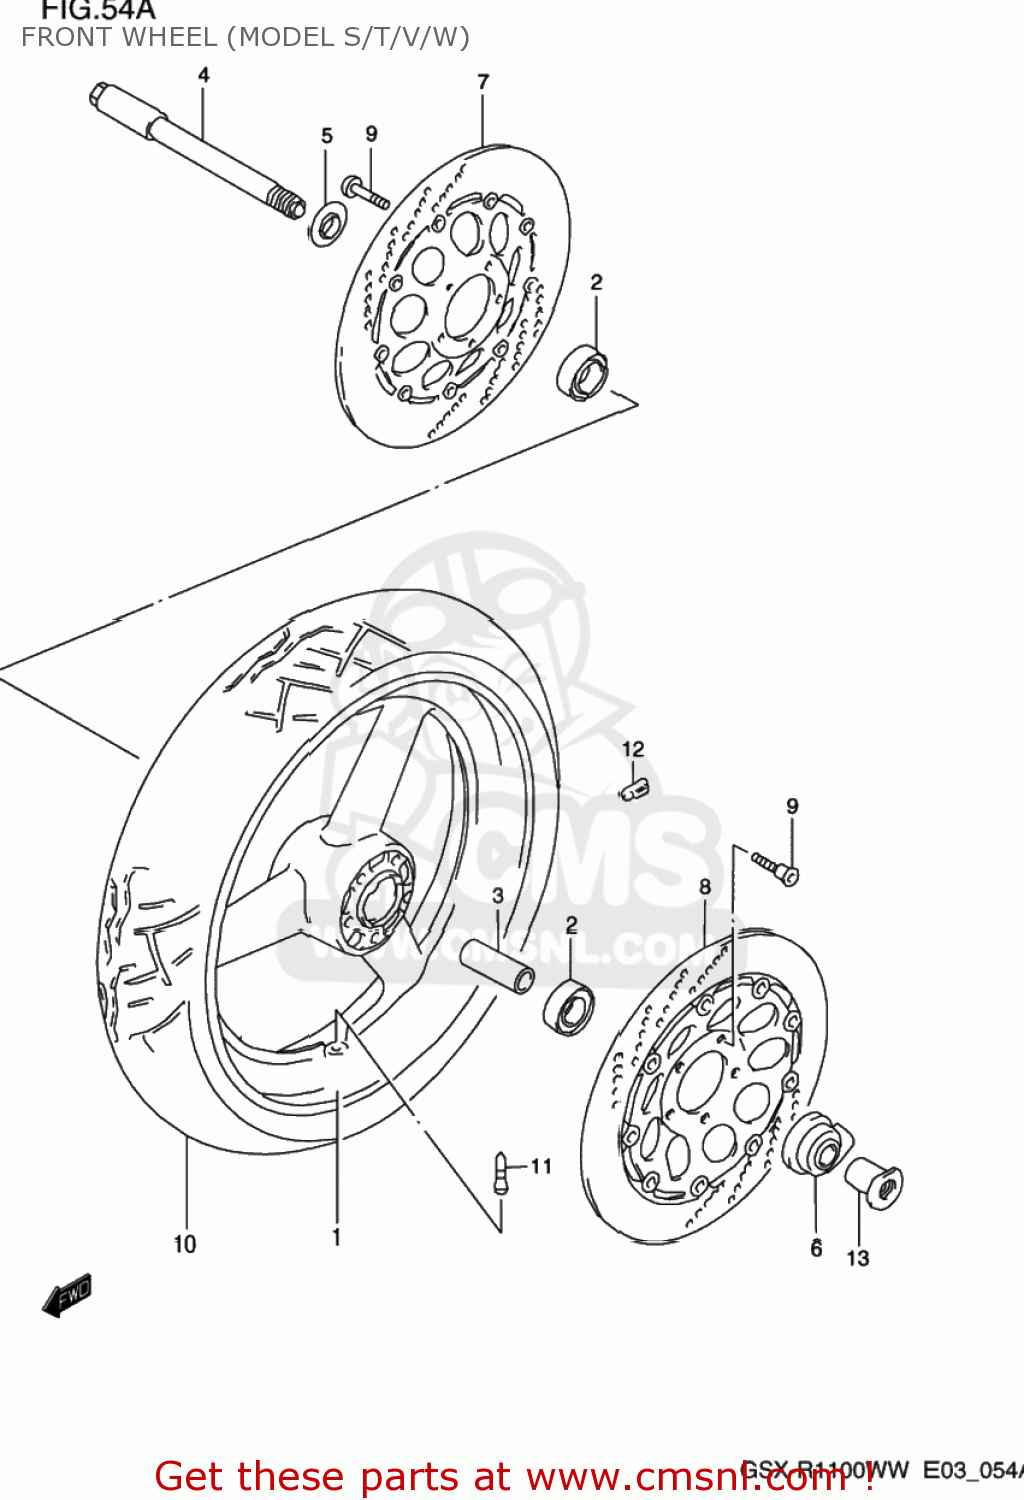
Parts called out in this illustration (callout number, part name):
1	WHEEL,FRONT (MT3.50X17)
2	BEARING
3	SPACER(20.8X27.2X74)
4	AXLE,FR
5	SPACER,FR HUB BEARING,R
6	BOX ASSY,SPEEDOMETER GEAR
7	DISC,FR BRAKE,R
8	DISC,FR BRAKE,L
9	BOLT 8X33
10	TIRE,FRONT
11	VALVE ASSEMBLY,WHEEL,TR412
12	BALANCER,WHEEL (10G)
13	NUT,FR AXLE
